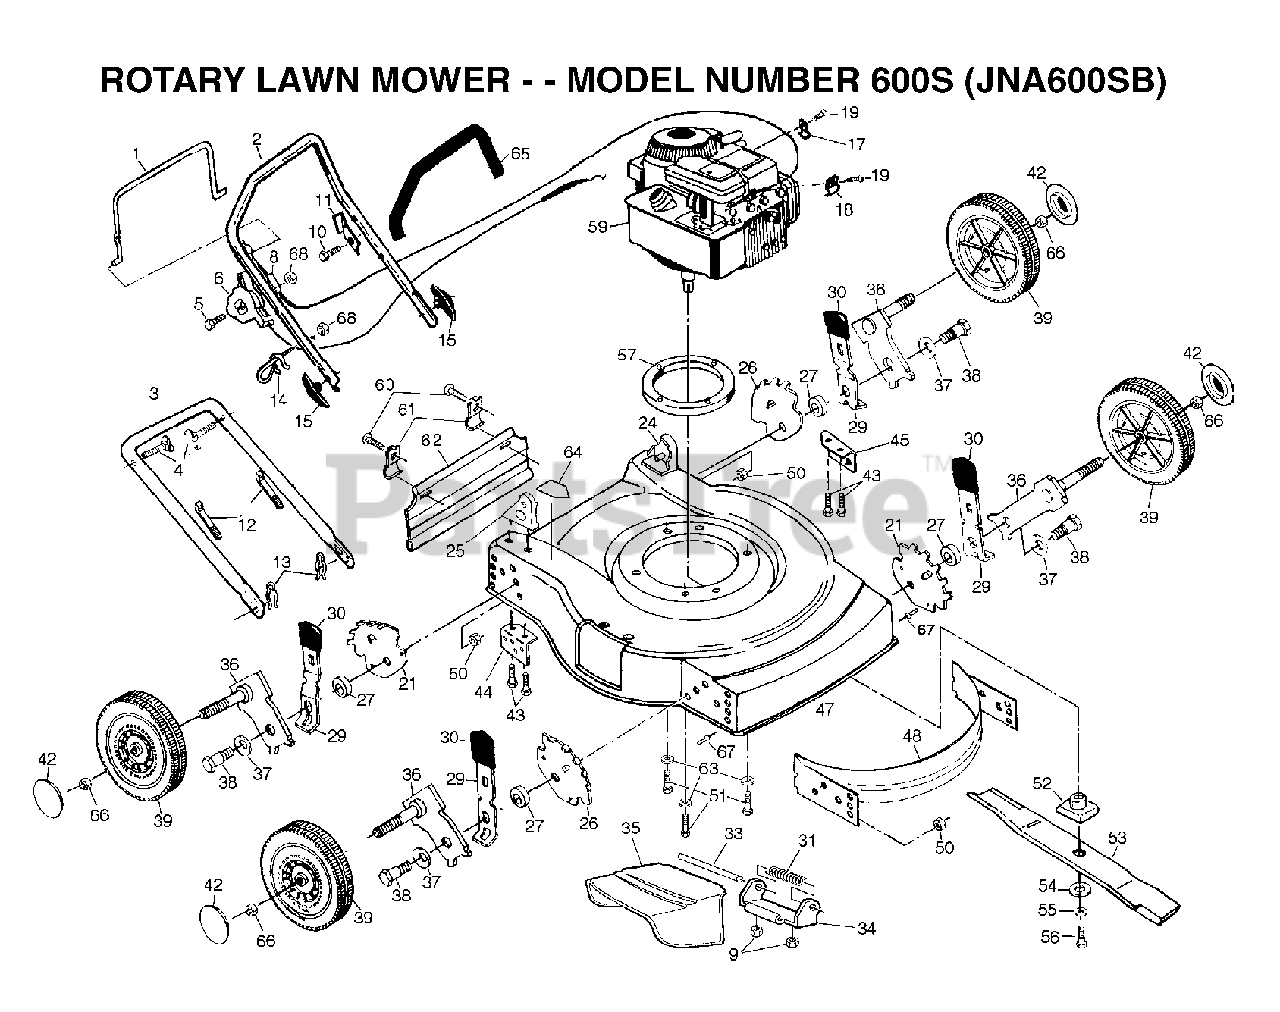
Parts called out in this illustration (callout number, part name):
1	CONTROL BAR
4	HANDLE BOLT
6	THROTTLE CONTROL
8	ENGINE ZONE CONTROL CABLE
9	NUT
11	BRACKET UPSTOP
12	TIE GUIDE
13	HAIRPIN COTTER
14	ROPE, GUIDE
15	HANDLE KNOB
17	GUIDE CLIP PM
18	CABLE CLAMP(ENGINE)
19	SCREW.HEX.HEAD.WASHER.10-16
21	BRACKET.WHL.ADJ.L
24	HANDLE BRACKET ASM. LH
25	HANDLE BRACKET ASM. RH
26	BRACKET.WHL.ADJ.R
27	RP SPACER HT ADJ
29	SELECTOR SPRING
31	SPRING PM
33	ROD.HINGE.COMBI-C
34	BRACKET PM
36	AXLE, REAR
37	BELLEVILLE WASHER
38	BOLT
43	SCREW 5/16-18
44	BRKT SUPPORT(R)
45	BRKT SUPPORT(L)
50	LOCKNUT PM
52	BLADE ADAPTOR
53	%20"BLADE (FOR MODELS 50/51)
54	WASHER,HARDEN
55	LOCKWASHER
56	SCREW, HEX HD 3/8-24 X 1-3/8
60	TAPPING SCREW
61	BRACKET DEFL PM
62	REAR SKIRT
66	HEX FLANGE LOCKNT
67	RIVET BLIND
68	NUT
